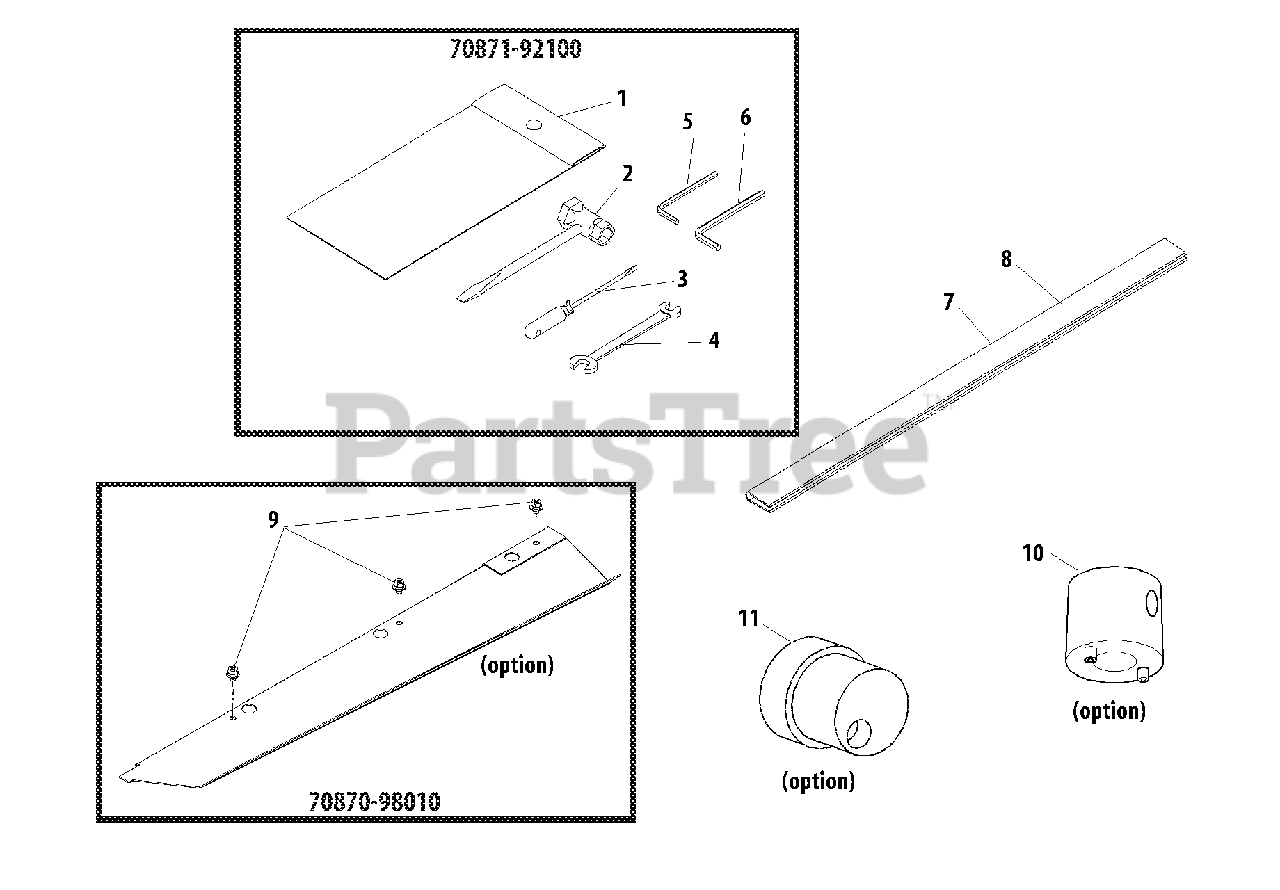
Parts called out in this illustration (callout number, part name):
1	BAG, TOOL
2	T-WRENCH 13×19 MM
3	SCREWDRIVER
4	SPANNER 8×10
5	WRENCH, ALLEN 4 MM
6	WRENCH, ALLEN 5 MM
7	SCABBARD 30"
8	SCABBARD 40"
9	BOLT M5×8
10	CLUTCH DRUM WRENCH
11	BEARING HOLDER
70870-98010	DEBRIS DEFLECTOR ASSY
70871-92100	SERVICE TOOL KIT
